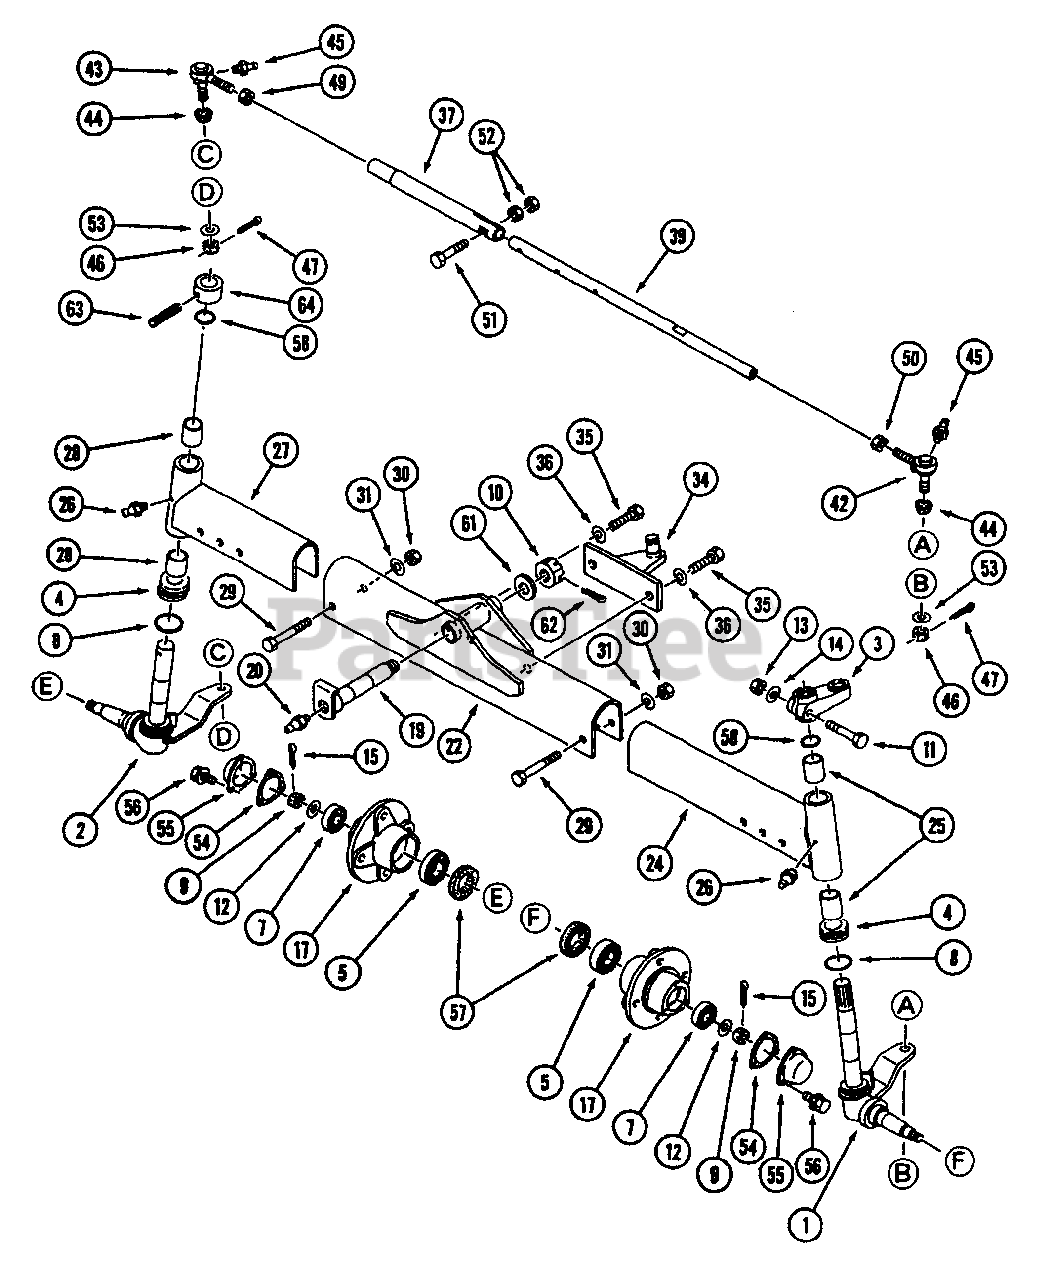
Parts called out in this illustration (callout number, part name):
1	Knuckle, L.H.
2	Knuckle, R.H.
12	Washer
17	Hub, Front Wheel
20	Nipple, Grease
22	Center, Front
26	Nipple, Grease
35	Bolt
37	Tube-Tie Rod (L.H. Thread)
39	Tube-Inner Tie Rod (R.H. Thread)
42	End Ass'y.-Tie Rod L.H. Side (R.H. Thread)
43	End Ass'y.-Tie Rod R.H. Side (L.H. Thread)
44	Cover, Dust
45	Nipple, Grease
49	Nut (L.H. Thread) M17
50	Nut (R.H. Thread) M17
51	Bolt
52	Nut
